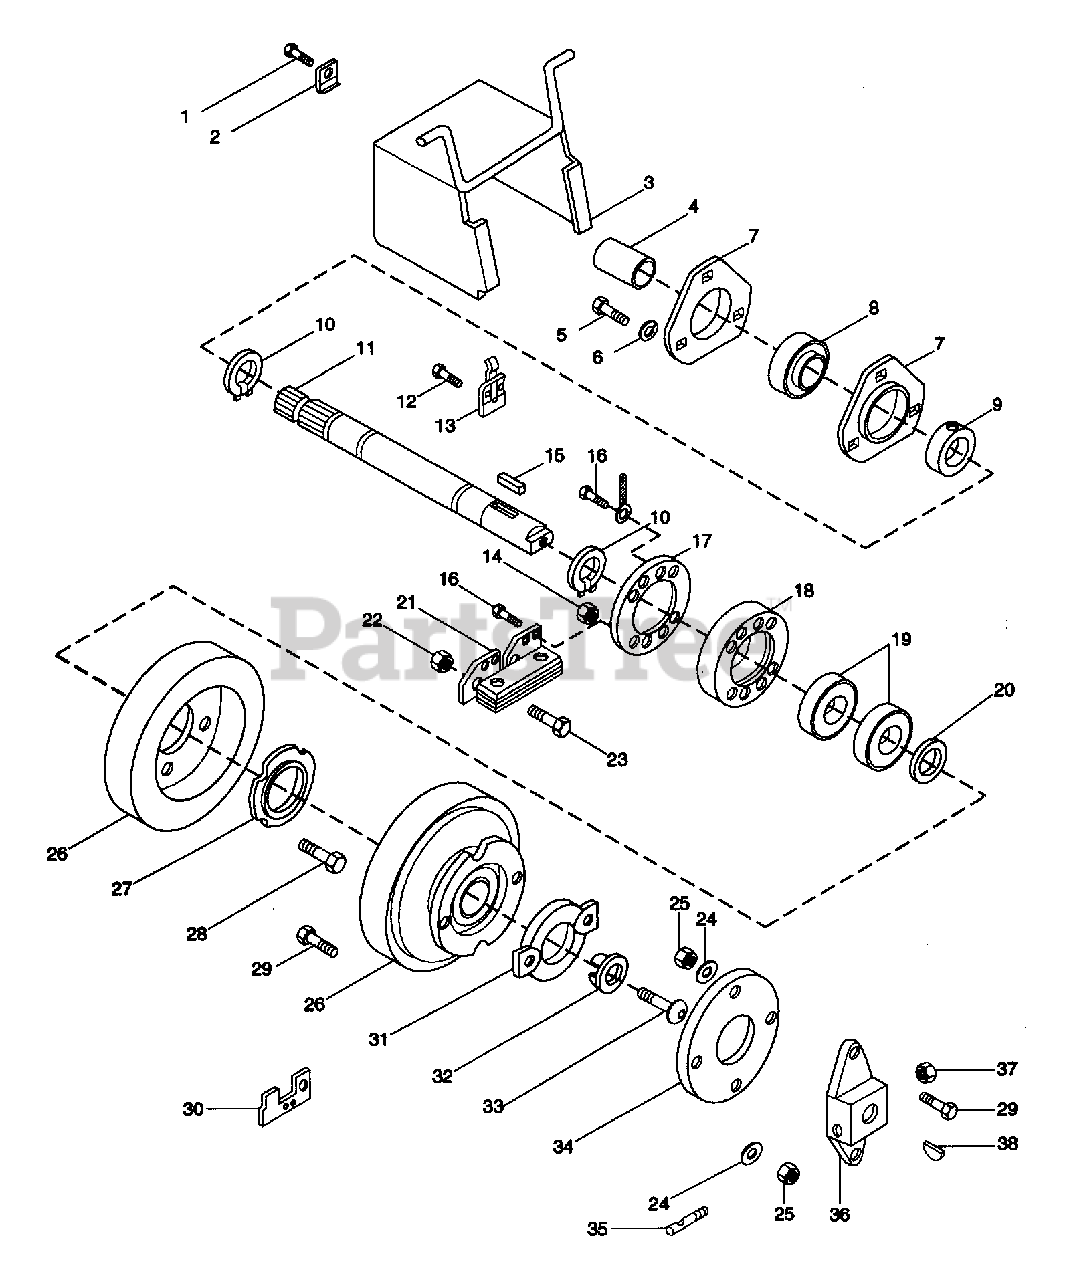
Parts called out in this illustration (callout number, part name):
1	SCR-TAP .250-20X.50 HXSLHDPL
3	PTO SHIELD
4	SHAFT COVER
5	BLT-HEX .31-18X.75 PL GR2
6	WSHR-LK .312X.097 PL HVY
7	BEARING FLANGE
8	BRG/W COLLAR 1.0 X 2.047 X.844
9	BEARING COLLAR
10	RG-RTNG-EXT 1.00X.078
12	SCR-TAP 10-24X.375 HWH PL TR
13	SNAP FASTENER
14	NUT-LK TOP 10-24 PL
15	KEY-SQ .25X1.0X.25 SAE 8630
16	SCR-TAP 10-24X.75 HWH PL TR
18	BEARING MOUNT
19	BRG-BALL 1.0X2.0X.56
20	WSHR-FL-STL 1.031X1.375X.055
21	TORQUE BRACKET ASSEMBLY
22	NUT-LK-CTR .312-24 PL
23	BLT-HEX .31-18X1.50 PL GR5
24	WSHR-FL-STL.344X.688X.065PL
25	NUT-LK .312-18 GR A PL
26	ELECTRIC CLUTCH
27	BEARING FLANGE
28	SCR-MCH 10-24X1.25 SLPAN PL
29	BLT-HEX .31-18X.88 PL GR2
30	CONNECTOR MOUNTING CLIP
31	PILOT PLATE
32	RETAINER
33	BLT-BTHD .38-16X1.25 GR5
34	SPACER COUPLING
35	LOCK STUD
36	COUPLING
37	NUT-LK TOP .375-16 GR C YWZC
38	KEY-WDRF .188X.75X.313 SAE 9
